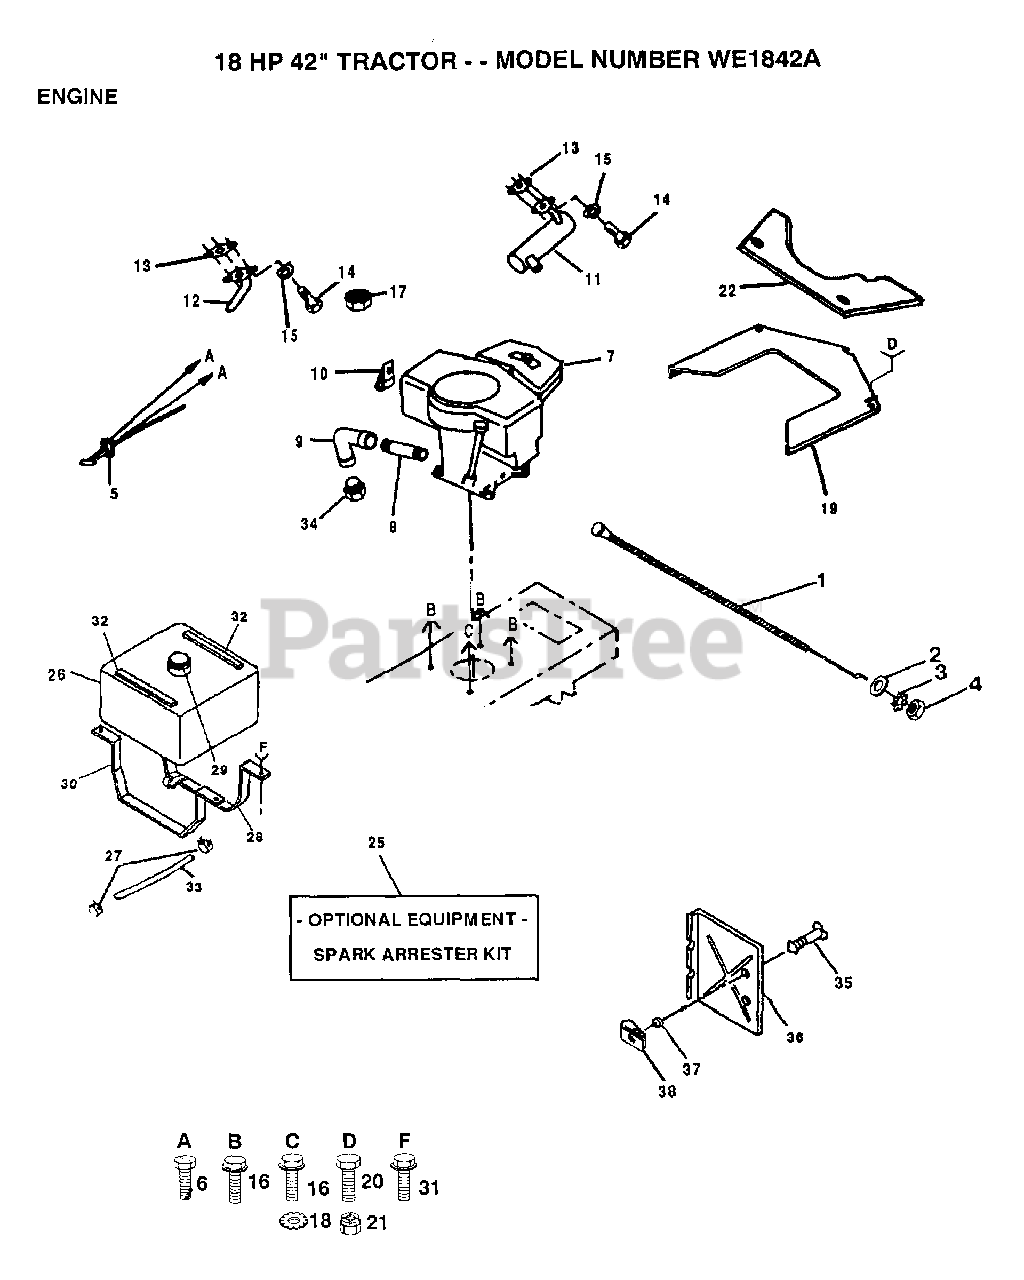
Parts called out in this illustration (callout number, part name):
1	CHOKE CONTROL
2	WASHER
3	LOCKWASHER
6	SCREW LT
8	PIPE NIPPLE LT
9	ELBOW
10	CLIP T
12	EXHAUST TUBE T
15	LOCKWASHER
16	SCREW LT
17	NUT
18	LOCKWASHER
19	SHIELD HEAT FRT
22	REAR BAFFLE T
25	SPARK ARREST KIT
27	HOSE CLAMP
28	STRAP ASM. F.TANK
30	"STRAP,TANK"
31	SCREW LT
32	"STRIP,FORM"
33	FUEL LINE T
35	STUD.1/4.TURN
36	HEAT SHIELD
37	RETAINER LT
38	RECEPTACLE LT
